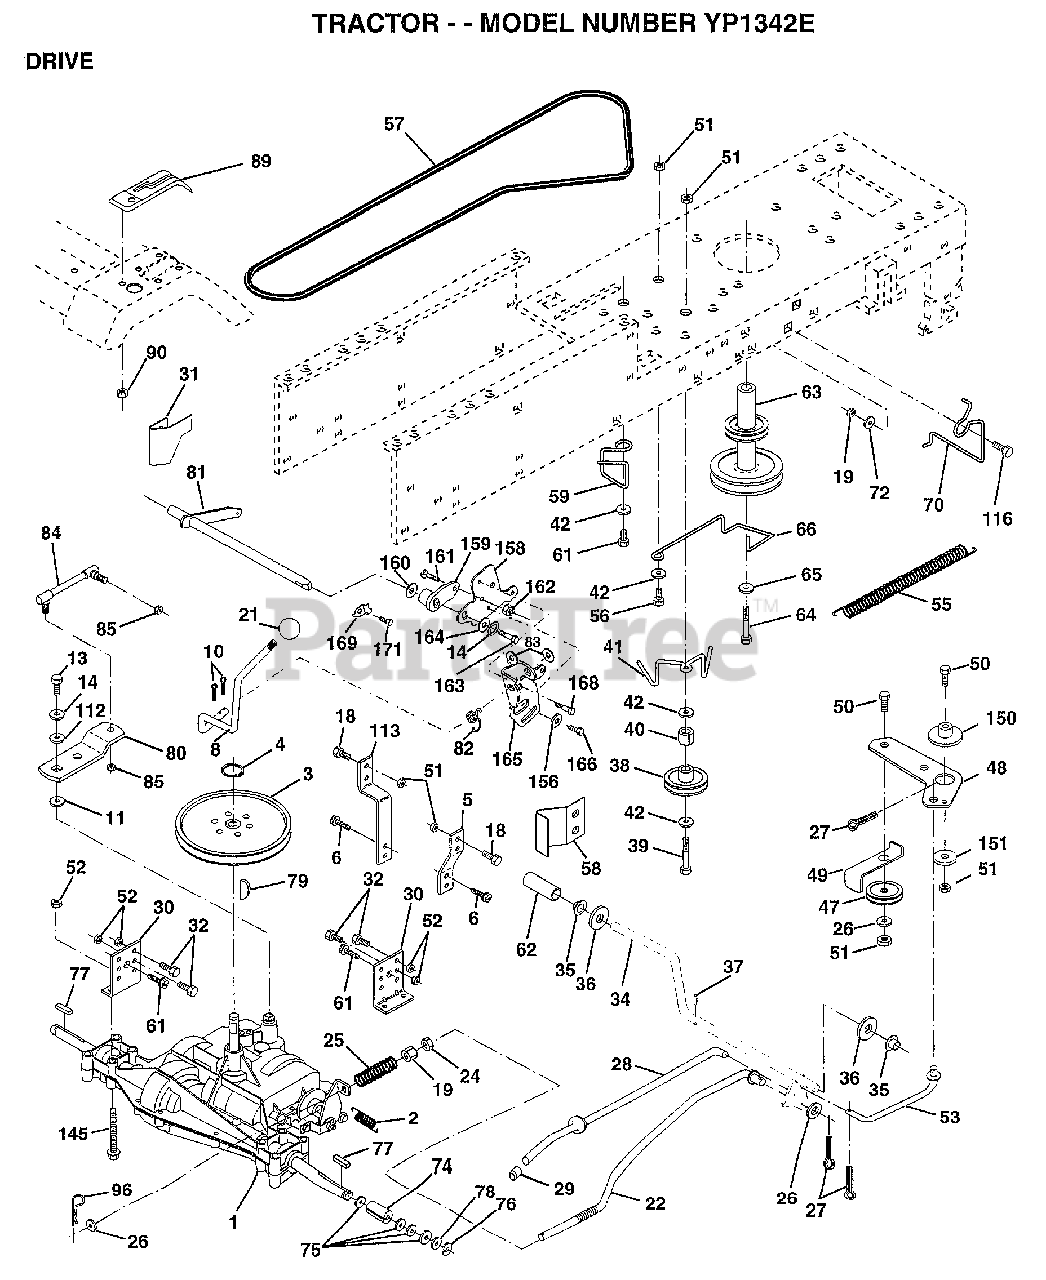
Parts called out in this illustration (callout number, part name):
2	SPRING.BRAKE.RETU
3	PULLEY TRANS
5	STRAP TORQUE
6	SCREW
8	ROD.SHIFT.FENDER.ADJ.LT.CRD
10	PIN COTTER 1/8
11	WASH-SHFT PLT LT
13	BOLT.1/4-28.W/PAT
14	LOCKWASHER
18	BOLT
19	NUT
21	KNOB.DUCKHEAD.1/2
22	BRAKE ROD
24	NUT
25	SPRING ROD LT
26	WASHER
27	COTTER PIN
28	ROD.BRAKE.PARK.LT
29	PLUNGER CAP T
30	TRANSAXLE MTG BKT
31	"KEEPER,BELT LH T"
32	BOLT
34	SHAFT ASM-PEDAL F
35	NYLON BEARING
36	WASHER LT
38	FLAT IDLER PULLEY
39	BOLT
40	SPACER T
41	"KEEPER,BELT.IDLER FLAT"
42	WASHER
48	BELLCRANK.CLUTCH
49	RETAIN BELT
53	"LINK, CLUTCH T"
55	"SPRING, RETURN LT"
58	"KEEPER,BELT RH T"
59	KEEPER BELT CNTSP
61	SCREW
62	PEDAL COVER T
63	PULLEY.ENGINE
64	BOLT
65	LOCKWASHER
66	KEEPER-BELT
70	KEEPER BELT ENG
72	WASHER
74	SPACER AXLE
75	WASHER
76	E-RING LT
77	SQUARE KEY
78	WASHER
80	"ROD,LINK SHIFT"
81	SHAFT.ASM.CROSS
82	"SPRING,TORSION"
83	WASHER
84	LINK.TRANSAXLE
85	NUT.CNT.LOCK.1/4
89	CONSOLE.SHIFT.SLT
90	NUT
96	RETAINER M
112	WASHER LT
113	"STRAP,TORQUE"
116	BOLT RDHD 3/8-16
145	BOLT.HEX.FLGHD
150	BUSHING.BELLCRANK.GRD.DR
151	WASHER
156	WASHER.SRRTD.5/16
158	BRKT.SHIFT.MOUNT
159	HUB.SHIFT
160	WASHER
161	BOLT T
164	WASHER.5/8X.281X10GA
165	BRACKET PIVOT LEVER
166	SCREW.5/16-18X5/8
168	BOLT.SHOULDER.5/16-18X.561
169	PLATE.FASTENING
171	SCREW LT
